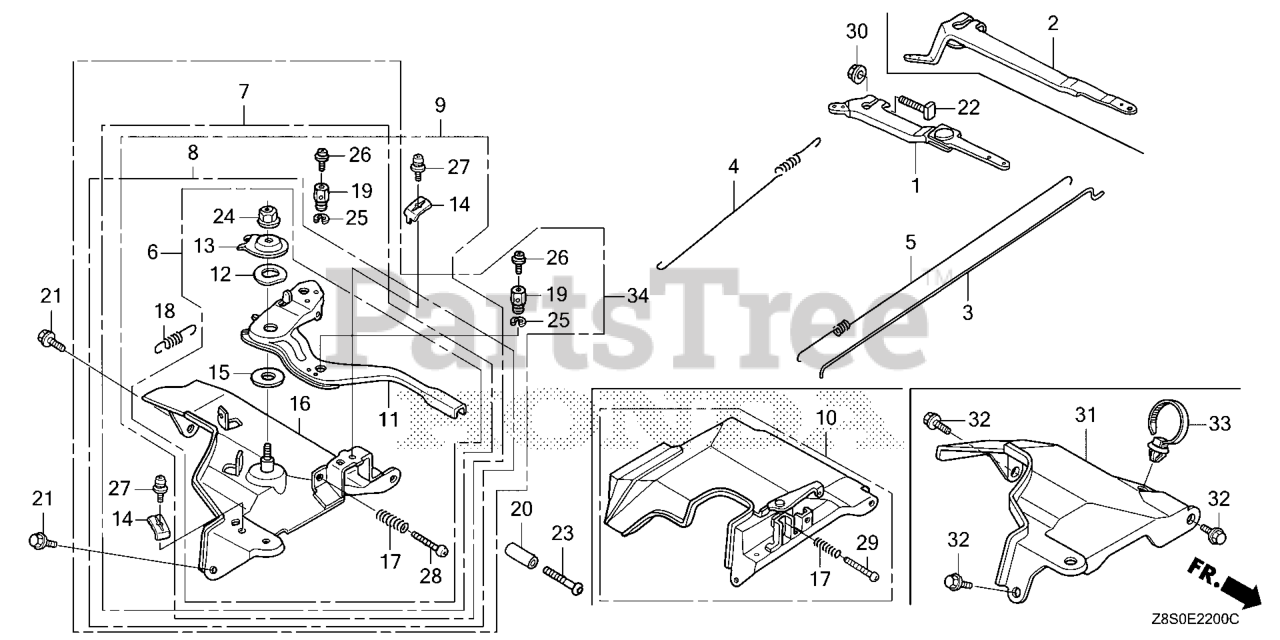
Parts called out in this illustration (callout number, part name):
2	ARM, GOVERNOR
3	ROD, GOVERNOR
4	SPRING, GOVERNOR (L=145.0MM) (WIRE DIAMETER 1.0MM)
5	SPRING, THROTTLE RETURN
11	LEVER, CONTROL
12	SPRING, LEVER
13	WASHER, CONTROL LEVER
14	HOLDER, CABLE
15	SPACER, CONTROL LEVER
16	BASE, CONTROL
17	SPRING, CONTROL ADJUSTING Use from Engine SN 2327377.
18	SPRING, CABLE RETURN
19	HOLDER, WIRE
21	BOLT, FLANGE (6X12) (CT200)
22	BOLT, GOVERNOR ARM
24	NUT, SELF-LOCK (6MM)
25	CIRCLIP (5MM) Use from Engine SN 2327377.
26	SCREW, PAN (4X6)
27	SCREW, PAN (5X16)
28	SCREW, PAN (5X28)
30	NUT, FLANGE (6MM)
34	CONTROL ASSY. (REMOTE)
